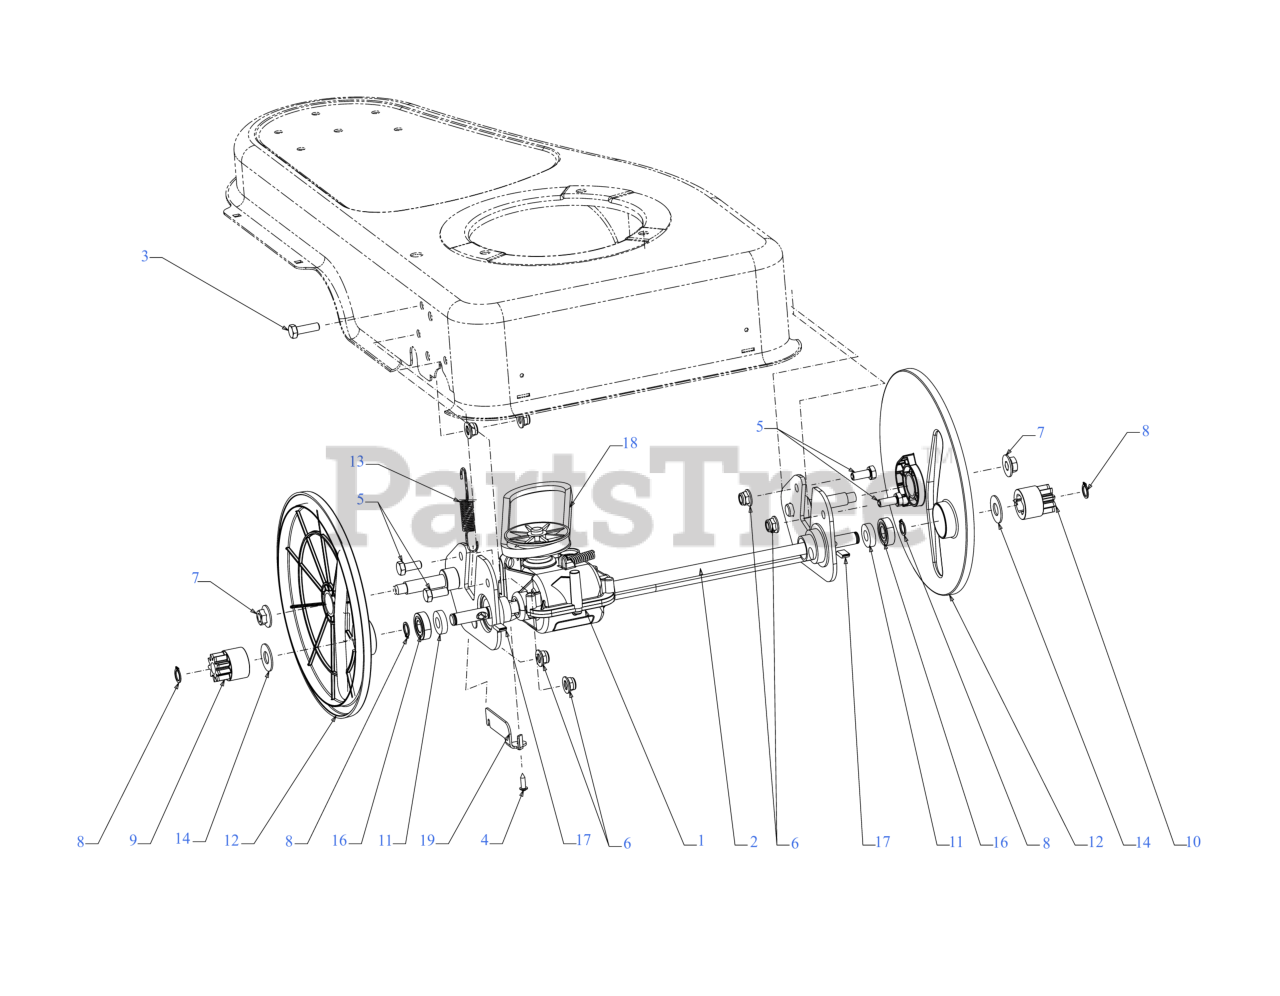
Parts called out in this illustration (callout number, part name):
1	TRANSMISSION
2	AXLE ASSEMBLY
3	SCREW 5/16-18 x 1.0 GR5
4	PAN HEAD SCREW M4.2X16
5	SCREW 5/16-18 x .75 GR5
6	FLANGE LOCK NUT 5/16-18
7	FLANGE LOCK NUT
8	EXT SNAP RING 12MM
9	SPUR GEAR 9T (LH)
10	SPUR GEAR 9T (RH)
12	DUST COVER
13	EXTENSION SPRING .500 OD x 3.375
14	FLAT WASHER
16	BALL BEARING
17	PINION GEAR PAWL
18	V-BELT-V 17.716"
19	SPRING BRACKET
